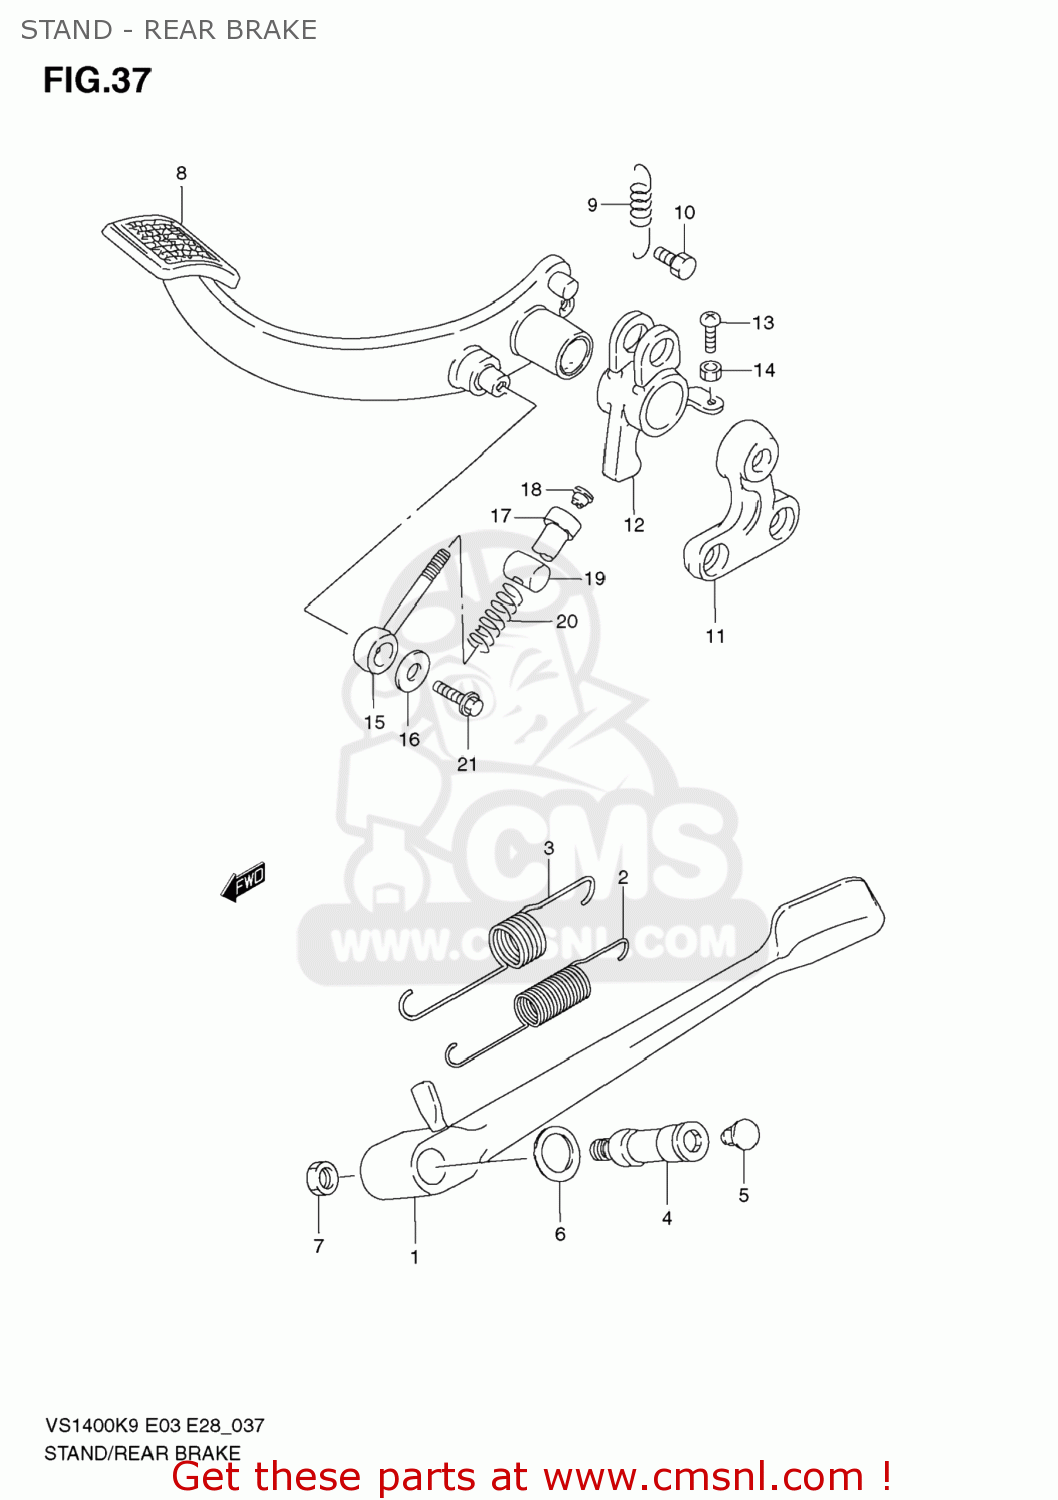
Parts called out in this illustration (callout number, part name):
1	STAND,PROP
2	SPRING
3	SPRING
4	BOLT,PROP STAND
5	CAP(OD:12)
6	SHIM(15X24X0.5)
7	NUT
8	PEDAL ASSY,BRAKE
9	SPRING
10	SCREW(6X10)
11	BRACKET,BRAKE PEDAL BOSS
12	ARM,RR BRAKE
13	SCREW(5X14)
14	NUT
15	LINK,BRAKE PEDAL
16	WASHER(6.5X18X1.5)
17	NUT,BRAKE PEDAL LINK
18	CAP(OD:10)
19	PIN
20	SPRING
21	BOLT
